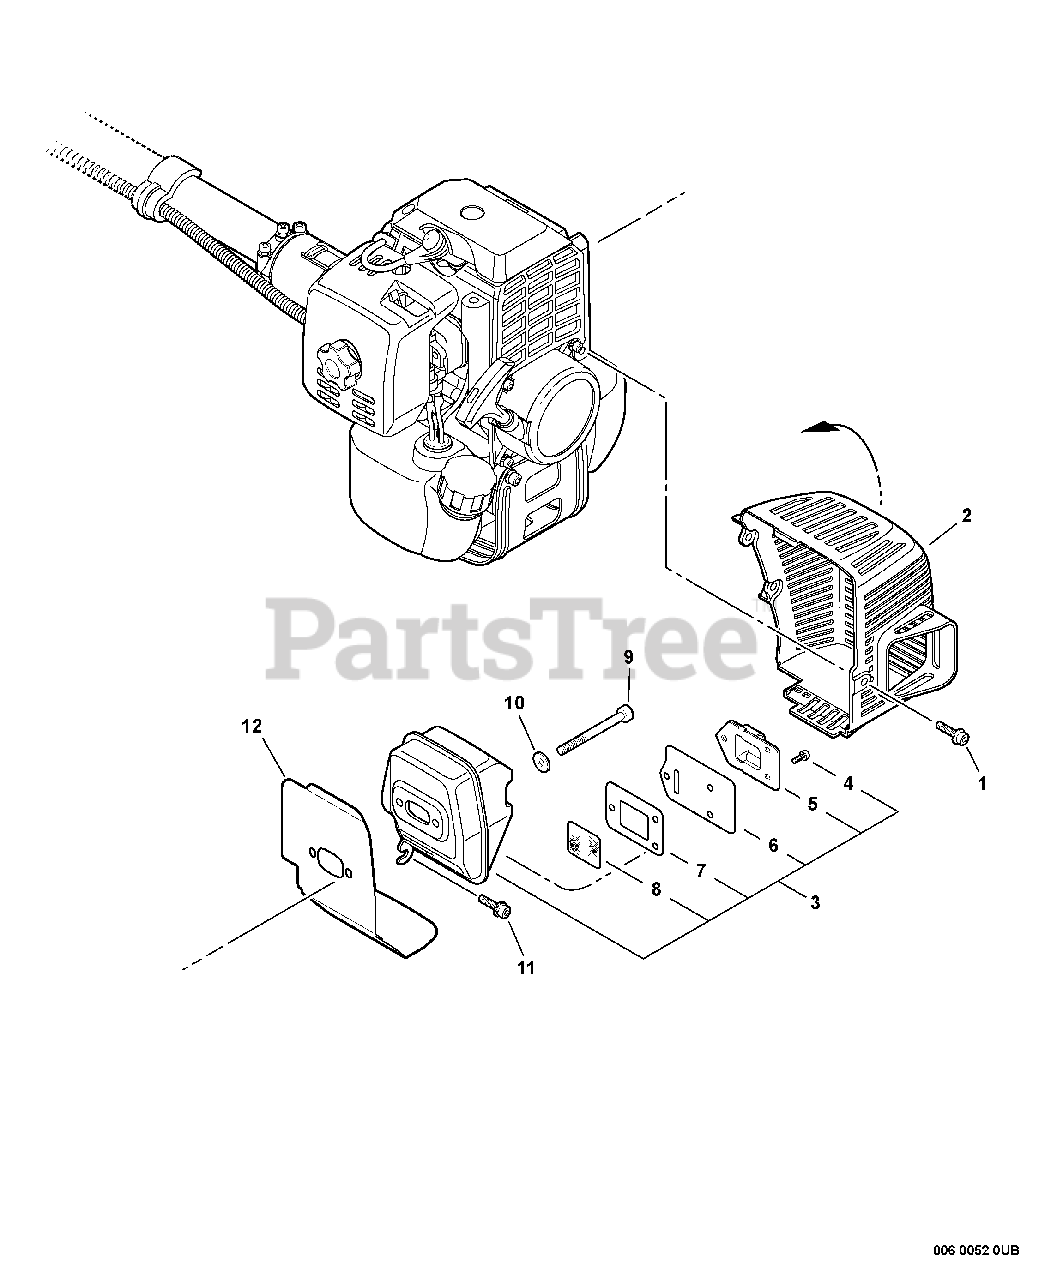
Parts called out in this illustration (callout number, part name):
1	SCREW - 5X14
2	COVER, EXHAUST
3	MUFFLER ASSY
4	SCREW - 4X12
5	GUIDE, EXHAUST
6	GASKET, EXHAUST
7	GASKET, EXHAUST
8	SCREEN, SPARK ARRESTOR
9	SCREW - 5X60
10	WASHER - 5
11	SCREW - 5X12
13	SHIELD, EXHAUST
